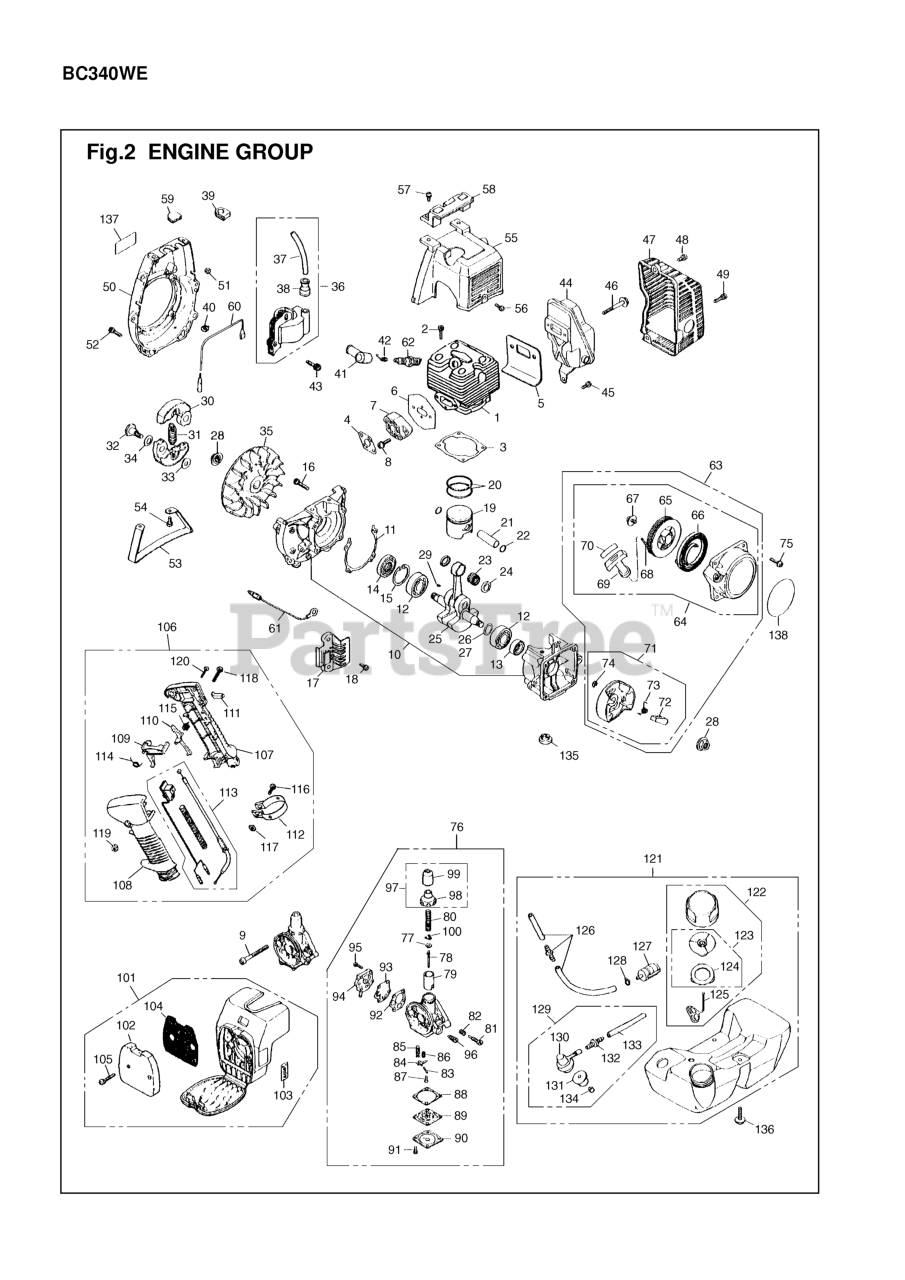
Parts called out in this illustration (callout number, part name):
1	CYLINDER (RPLS -12111)
2	BOLT
3	GASKET
7	INSULATOR
10	CRANKCASE (RPLS -21101)
13	SEAL, OIL (RPLS 1100-21210)
14	SEAL
15	RING, SNAP, M32 x 1.2
16	BOLT, M5 X 30
17	GUARD (RPLS-21310)
20	RING, PISTON
21	PIN
22	RING, SNAP
23	BEARING
24	WASHER
25	CRANKSHAFT CO
28	NUT
29	KEY
30	SHOE, CLUTCH (RPLS -51110)
31	SPRING, CLUTCH
32	SCREW
33	WASHER
34	WASHER (USE -51241)
36	COIL ASSEMBLY
38	CAP
39	GROMMET
42	SPRING
47	COVER, MUFFLER
48	BOLT
49	BOLT
50	COVER, FAN
52	BOLT
54	BOLT
55	COVER, CYLINDER (RPLS-32112)
58	HEAD GUARD
61	EARTH CORD
63	STARTER ASSY
64	RECOIL ASSEMBLY
65	REEL
66	SPRING, SPIRAL
67	SCREW (RPLS -75150)
69	KNOB
71	PULLEY ASSEMBLY
72	RATCHET
73	SPRING, RETURN
74	E-RING
76	CARBURETOR (RPLS -81002)
77	RETAINER SPRING
81	SCREW (RPLS -81161)
84	ARM, FLOAT
85	VALVE (REPLACES-81210)
86	SPRING, INLET
87	SCREW, FLOAT
88	GASKET (NLA)
89	DIAPHRAGM
92	GASKET, PUMP
93	DIAPHRAGM
94	COVER ASSY PU
96	NEEDLE (NLA)
98	CAP, MIXING
99	SEAL, AIR
100	CLIP (RPLS-81410)
101	CLEANER ASSY (USE -82002)
102	ELEMENT
103	LABEL
109	LEVER
110	LEVER
112	BAND
113	CABLE COMP
114	SPRING
115	SPRING
117	NUT
119	NUT
120	SCREW
121	TANK ASSY
122	CAP ASSY
123	VALVE COMP
124	PACKING (RPLS -85321)
125	STOPPER (RPLS 3317-57240)
126	PIPE ASSEMBLY
127	FILTER ASSY
128	CLIP
129	PUMP (RPLS -85600)
134	VALVE (RPLS -85650)
135	WASHER
136	SCREW, M5 X 22
137	LABEL, COVER
